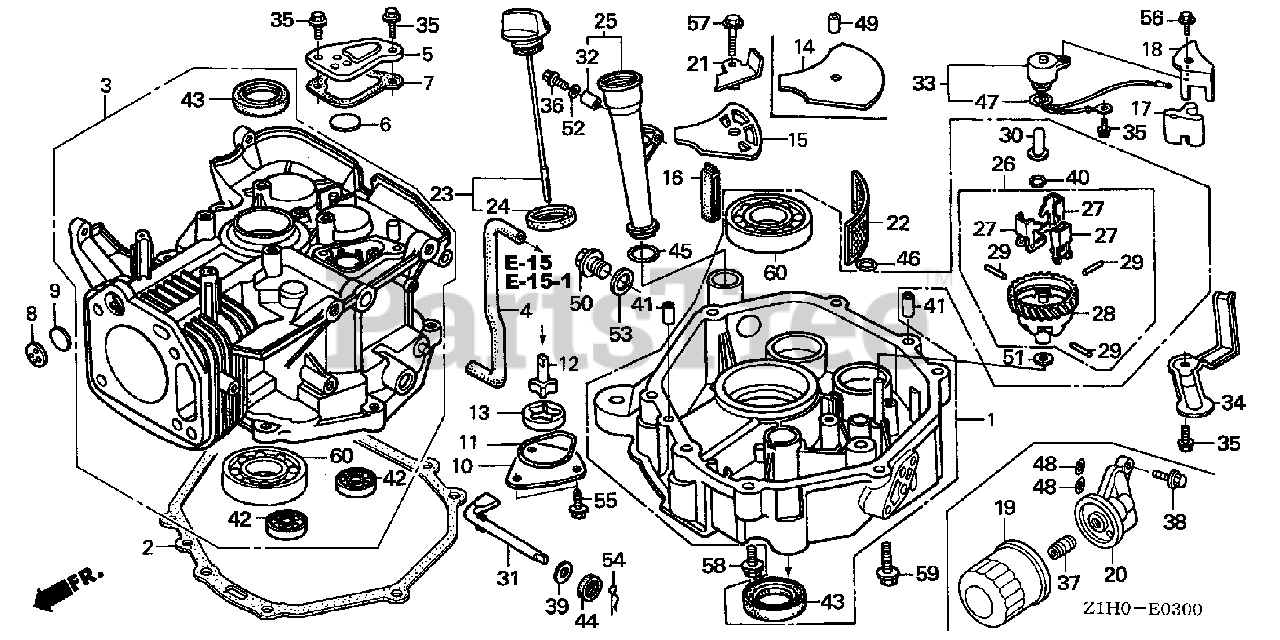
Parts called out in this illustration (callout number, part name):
1	PAN ASSY., OIL
2	GASKET, OIL PAN
3	CYLINDER ASSY.
4	TUBE, BREATHER
5	CAP, BREATHER CHAMBER
6	VALVE, BREATHER
7	GASKET, BREATHER CAP
8	PLATE, ONE-WAY VALVE
9	VALVE, ONE-WAY
10	COVER, OIL PUMP
11	O-RING, PUMP COVER
12	ROTOR (INNER)
13	ROTOR, OIL PUMP (OUTER)
15	PLATE, OIL FILTER
16	RUBBER, OIL RETURN
17	STOPPER, OIL
18	PLATE, OIL STOPPER
21	PLATE, SUCTION
22	SCREEN, OIL FILTER
23	CAP ASSY., OIL FILLER
24	GASKET, OIL FILLER CAP
25	EXTENSION, OIL FILLER
26	GOVERNOR ASSY.
27	WEIGHT, GOVERNOR
28	HOLDER, GOVERNOR WEIGHT
29	PIN, GOVERNOR WEIGHT
30	SLIDER, GOVERNOR
31	SHAFT, GOVERNOR ARM
32	COLLAR, EXTENSION
33	SWITCH, OIL LEVEL
34	PROTECTOR, SWITCH
35	BOLT, FLANGE (6X12) (CT200)
36	BOLT, FLANGE (6X35) (CT200)
39	WASHER, THRUST (8.1MM)
40	CLIP, GOVERNOR HOLDER
41	PIN, DOWEL (8X12)
42	BEARING, RADIAL BALL (6202)
43	OIL SEAL (35X52X8)
44	OIL SEAL (8X14X5)
45	O-RING (22.1X2.2)
46	O-RING (11.8X2.4)
47	O-RING (11.8X2.4)
50	BOLT, DRAIN PLUG (20MM)
51	WASHER, PLAIN (6MM)
52	WASHER, PLAIN (6MM)
53	WASHER, DRAIN PLUG (20MM)
54	PIN, LOCK (10MM)
55	BOLT, FLANGE (6X12)
56	BOLT, FLANGE (6X16)
57	BOLT, FLANGE (6X25)
58	BOLT, FLANGE (8X40)
59	BOLT, FLANGE (8X60)
60	BEARING, RADIAL BALL (6207)
